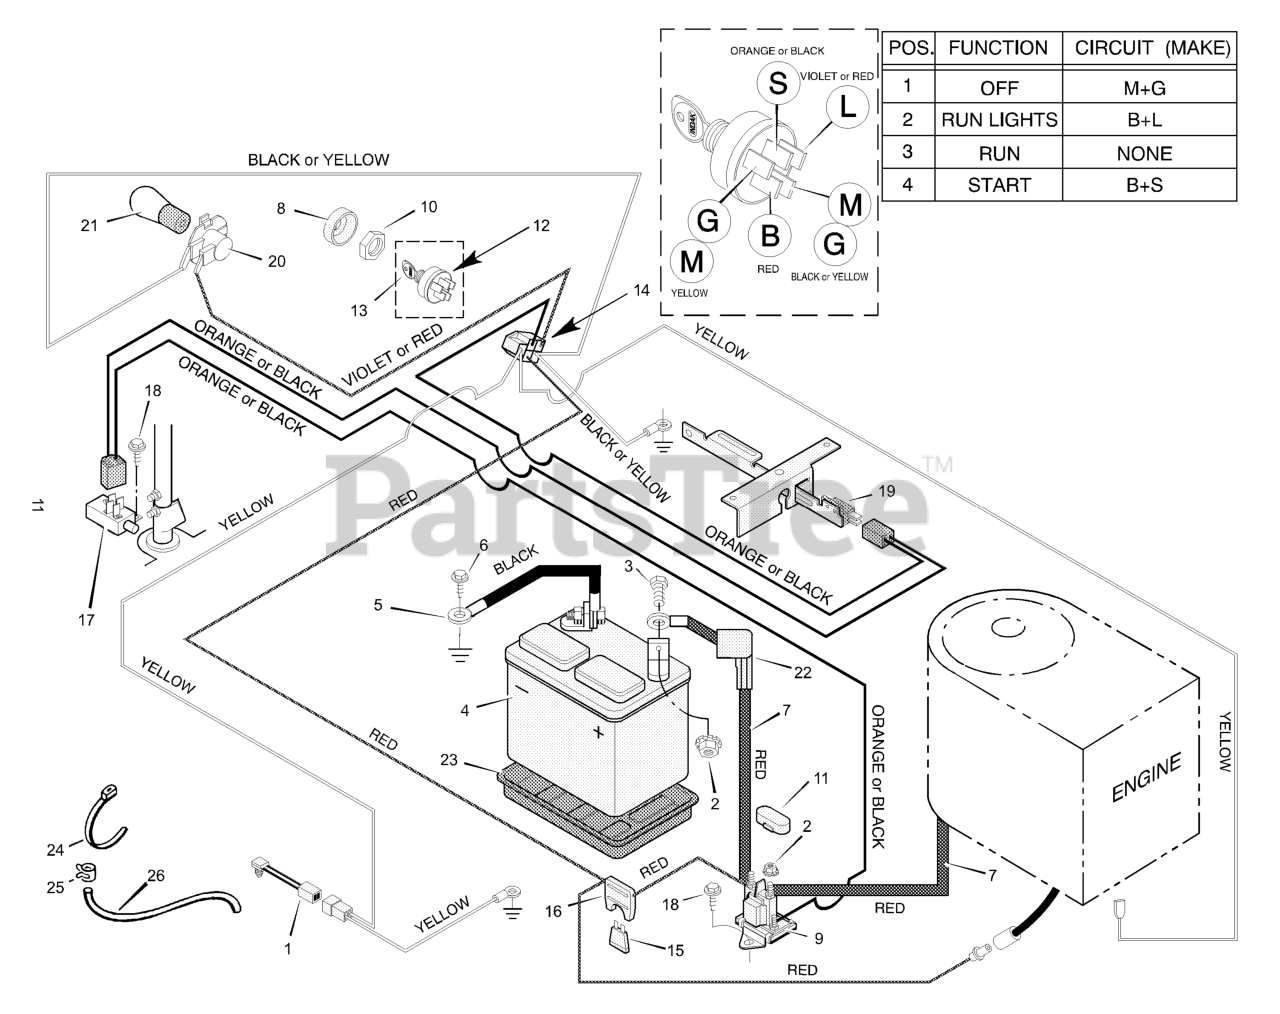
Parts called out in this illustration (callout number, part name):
1	Switch, Seat Sensor
2	Locknut
4	Battery
5	Cable, Battery Ground
7	Cable, Red Battery
8	Cap, Ignition
9	Solenoid
10	Nut, Hex
11	Cover, Solenoid
12	Switch, Ignition
13	Key, Ignition
14	Harness, Chassis Wire
16	Holder, Fuse
17	Switch, Limit
19	Switch, Limit
20	Socket, Light
21	Bulb, Light
22	Cover, Terminal
23	Tray, Battery
26	Tube, Drain
